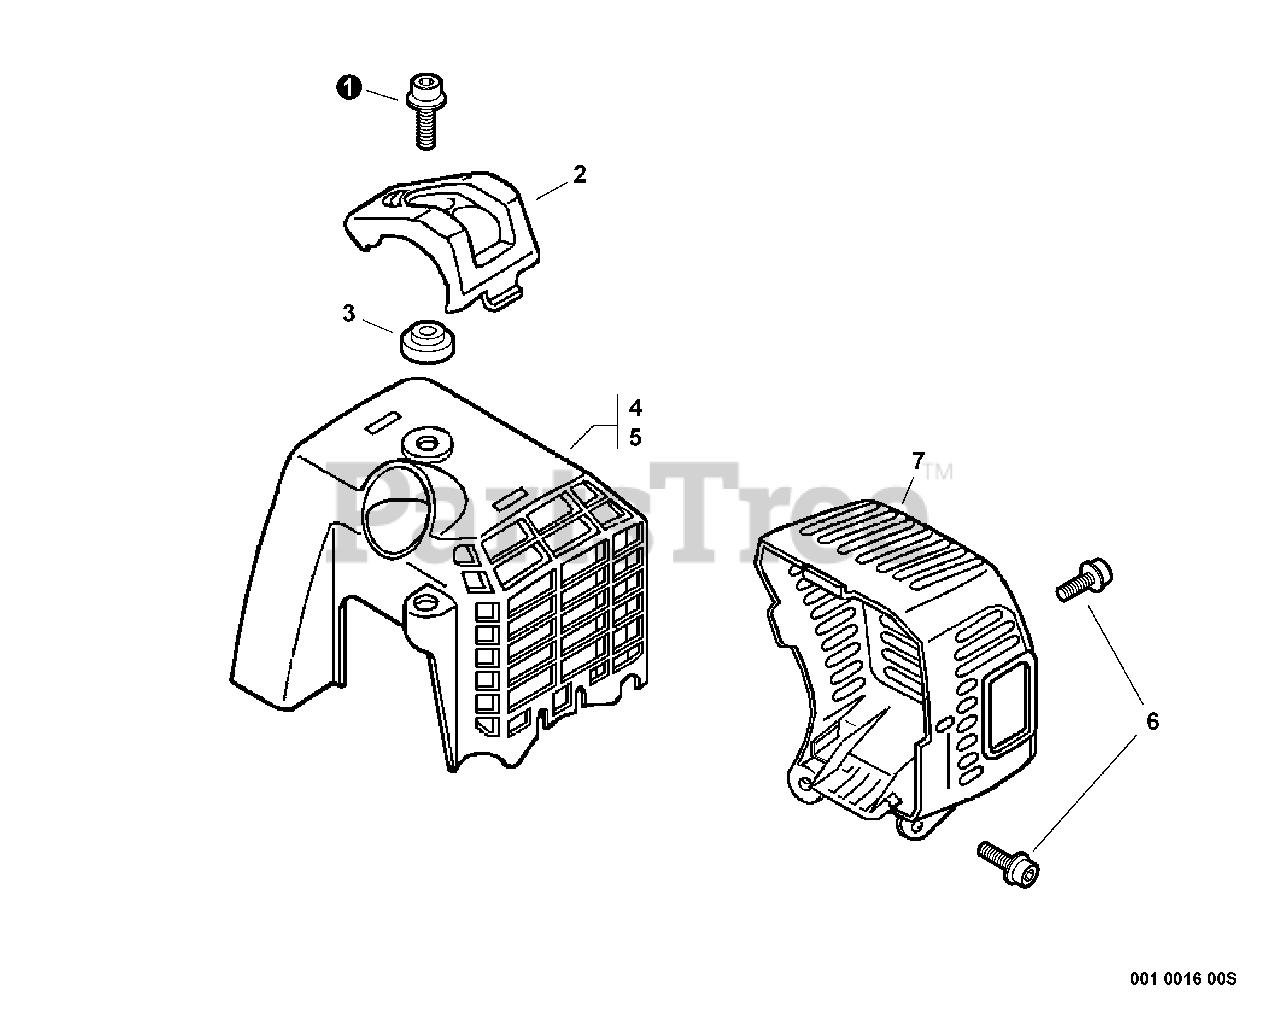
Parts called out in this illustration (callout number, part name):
1	BOLT 5×16
2	GUARD, TOP
3	COLLAR 5
4	COVER, ENGINE
5	COVER, ENGINE - ORANGE
6	BOLT 5×12
7	COVER, MUFFLER
